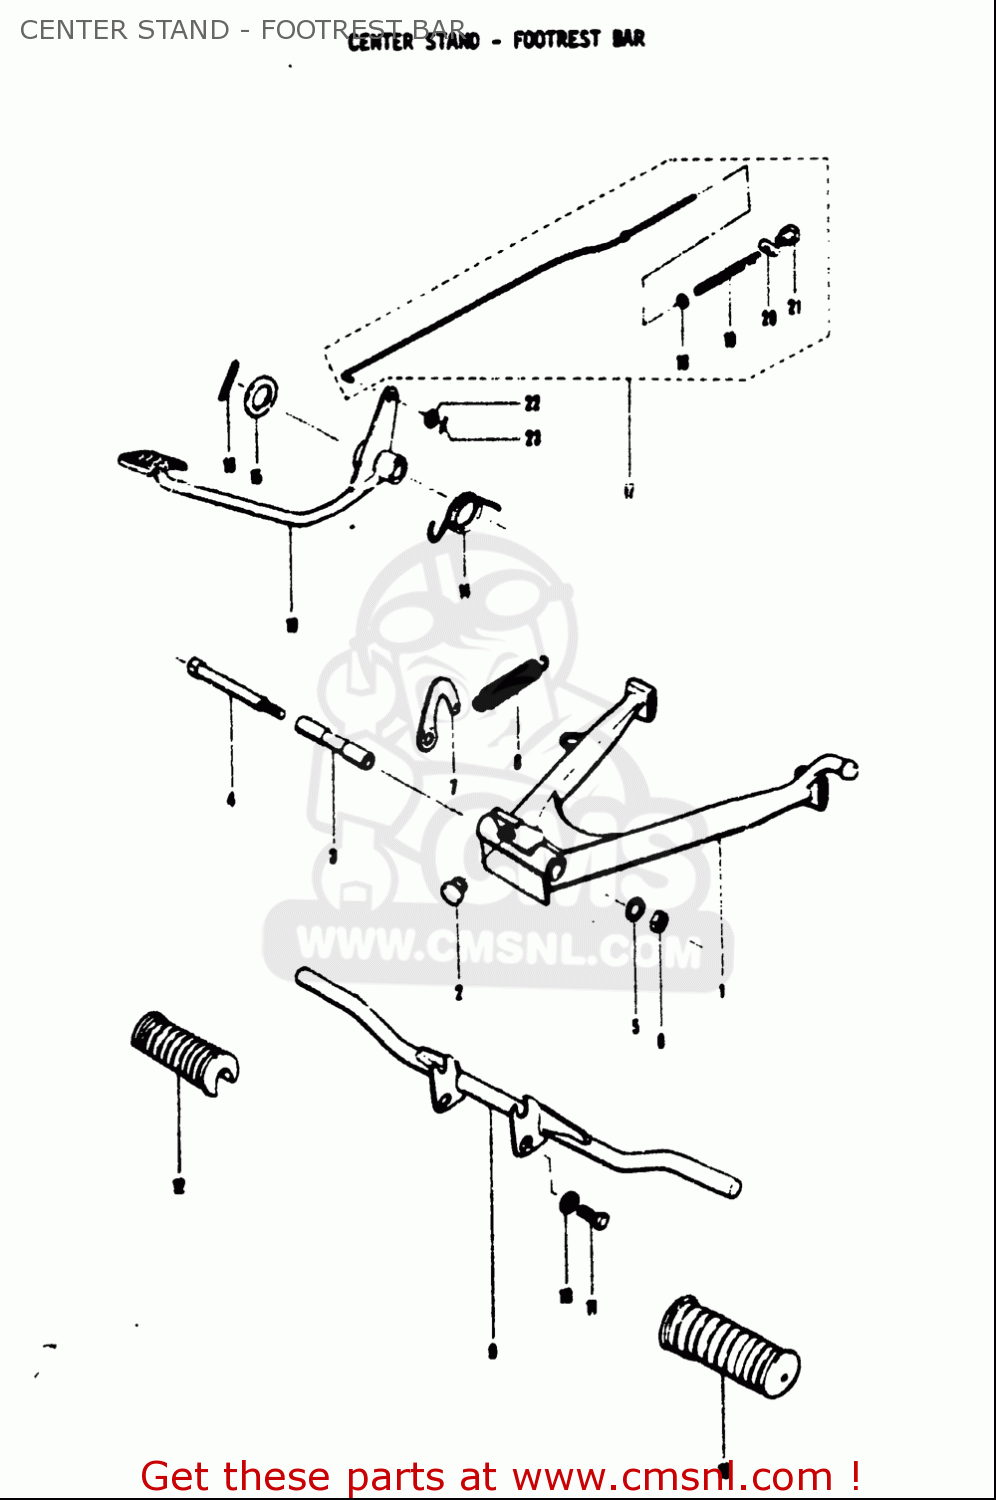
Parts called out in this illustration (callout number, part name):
2	CUSHION(11.5X22X20)
3	SPACER
4	BOLT
5	WASHER,LOCK
6	NUT
7	HOOK,CENTER STAND SPRING
8	SPRING
10	WASHER,LOCK
11	BOLT
12	RUBBER,FR FOOTREST
15	WASHER(15.5X26X2.3)
16	PIN
18	WASHER
19	SPRING
20	PIN(11X18)
21	NUT
22	WASHER
